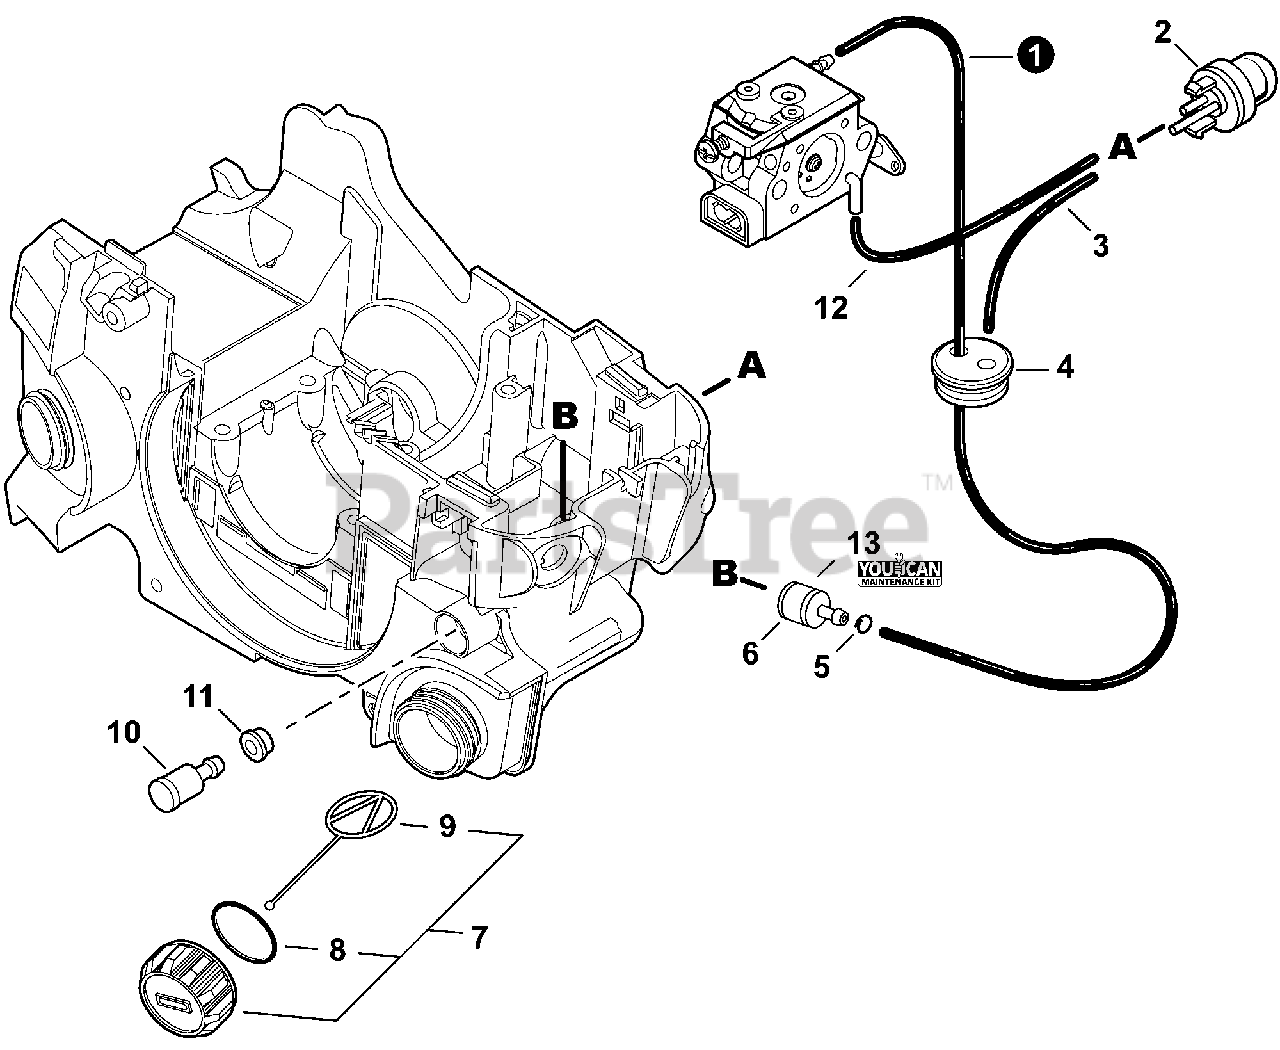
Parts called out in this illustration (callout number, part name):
1	PIPE, FUEL 3×5×230 BLACK
2	BULB, PURGE
3	PIPE, FUEL 2.4×5×80 BLACK
4	GROMMET, FUEL
5	CLIP 6 MM
6	FILTER, FUEL
7	CAP ASSY, FUEL
8	O-RING 22
9	CONNECTOR, CAP L= 60 MM
10	VENT ASSY
11	GROMMET, FUEL
12	PIPE 2.4×5×105 BLACK
13	TUNE-UP KIT - YOUCAN™
